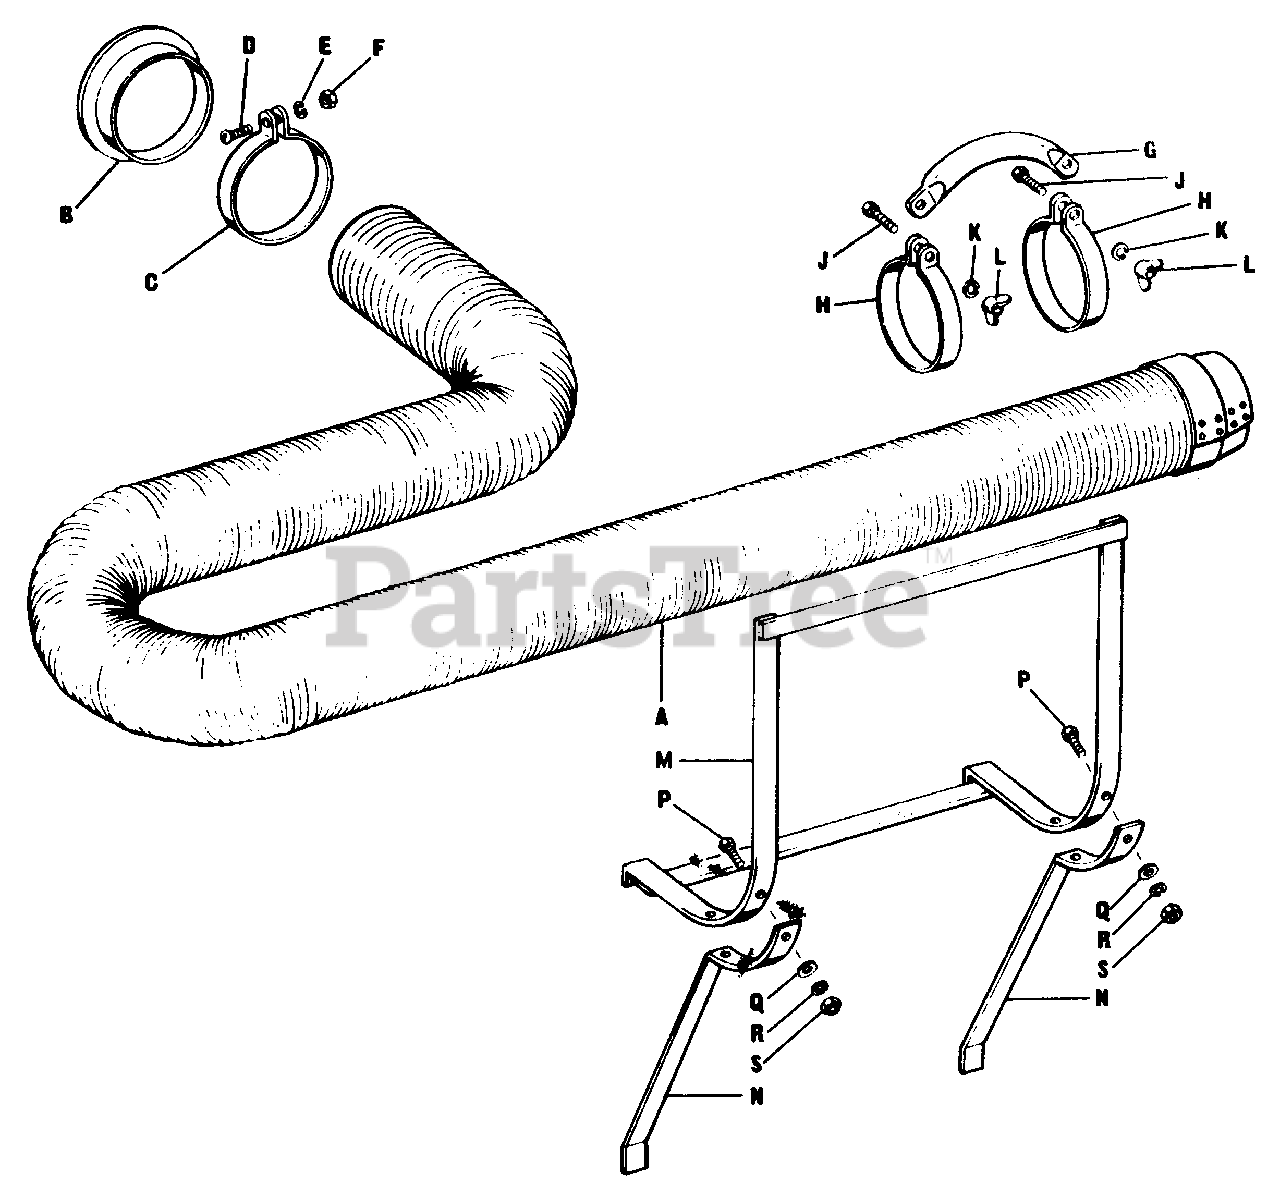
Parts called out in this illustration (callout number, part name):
A	Hose Assembly
B	Hose Flange
C	Hose Clamp
D	Rnd. Slot. Hd. Machine Screw, 1/4"-20 x 3"
E	Lock Washer 1/4"
F	Full Hex. Nut, 1/4"-20
G	Hose Handle
H	Hose Clamp Handle
J	Hex. Cap Screw, 5/16"-18 x 3/4"
K	Lock Washer, 5/16"
L	Wing Nut, 5/16"-18
M	Hose Carrier Assembly
N	Carrier Support
P	Hex. Cap Screw, 5/16"-18 x 7/8"
Q	Plain Washer, 5/16"
R	Lock Washer, 5/16"
S	Full Hex. Nut, 5/16"-18
